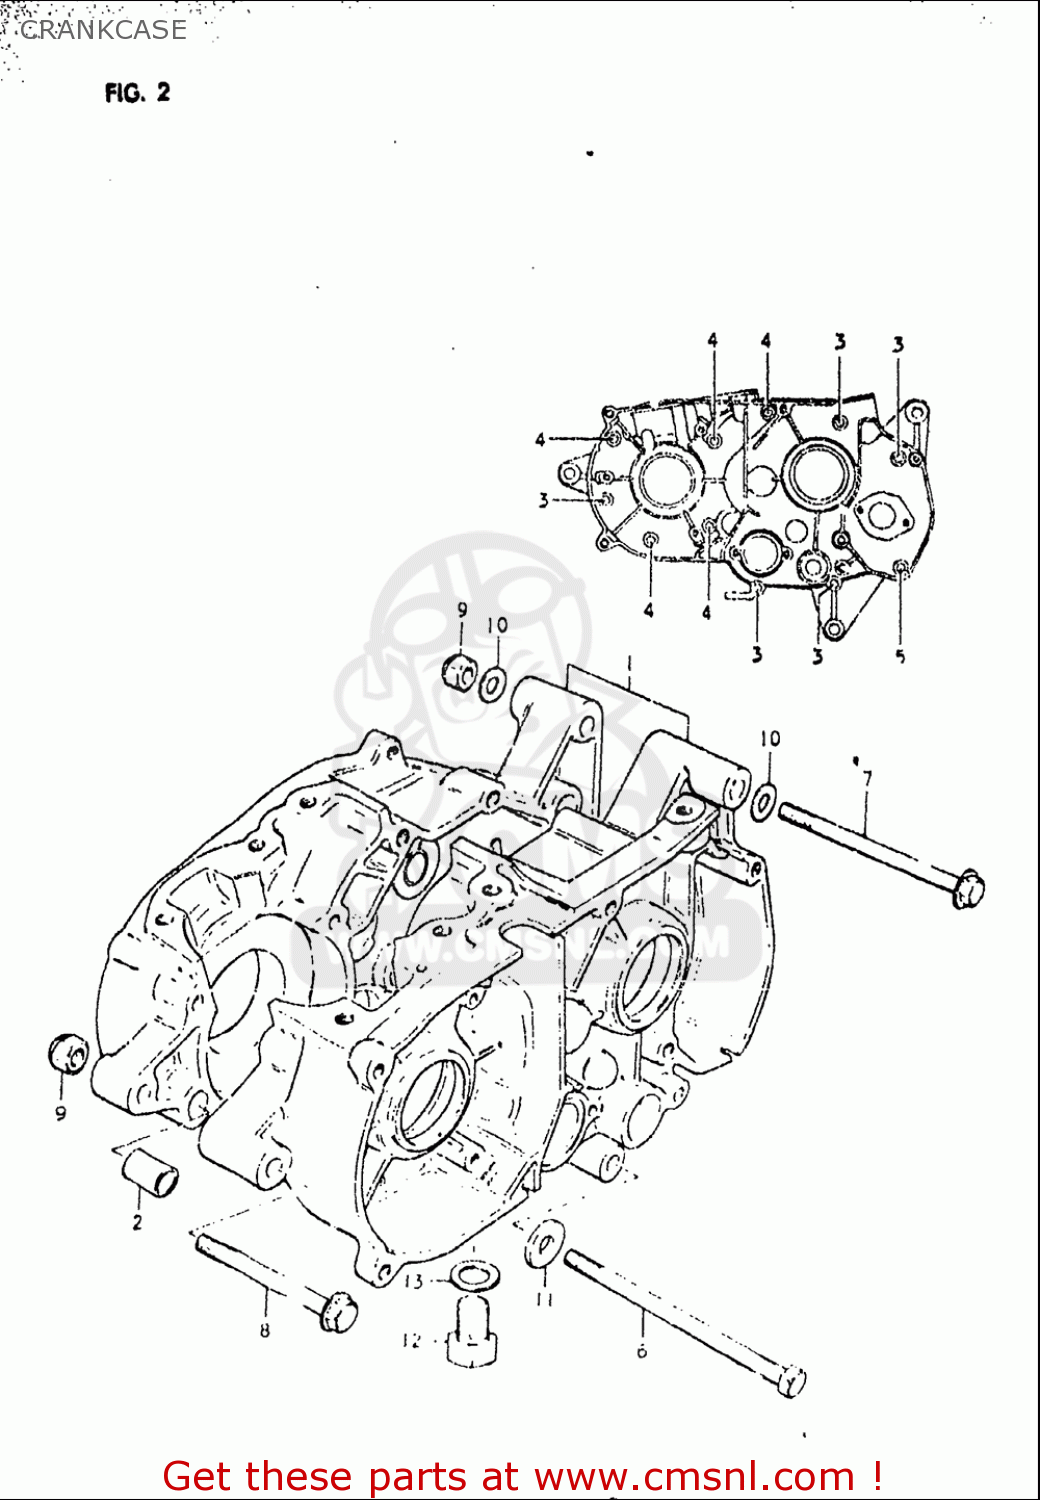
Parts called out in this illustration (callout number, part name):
2	PIN
3	SCREW
4	SCREW
5	SCREW
6	BOLT(8X115)
7	BOLT(8X100)
8	BOLT
9	NUT
10	WASHER
11	WASHER (8.2X22X3.2)
12	BOLT
13	GASKET(10X14X3.6) (NAS)
